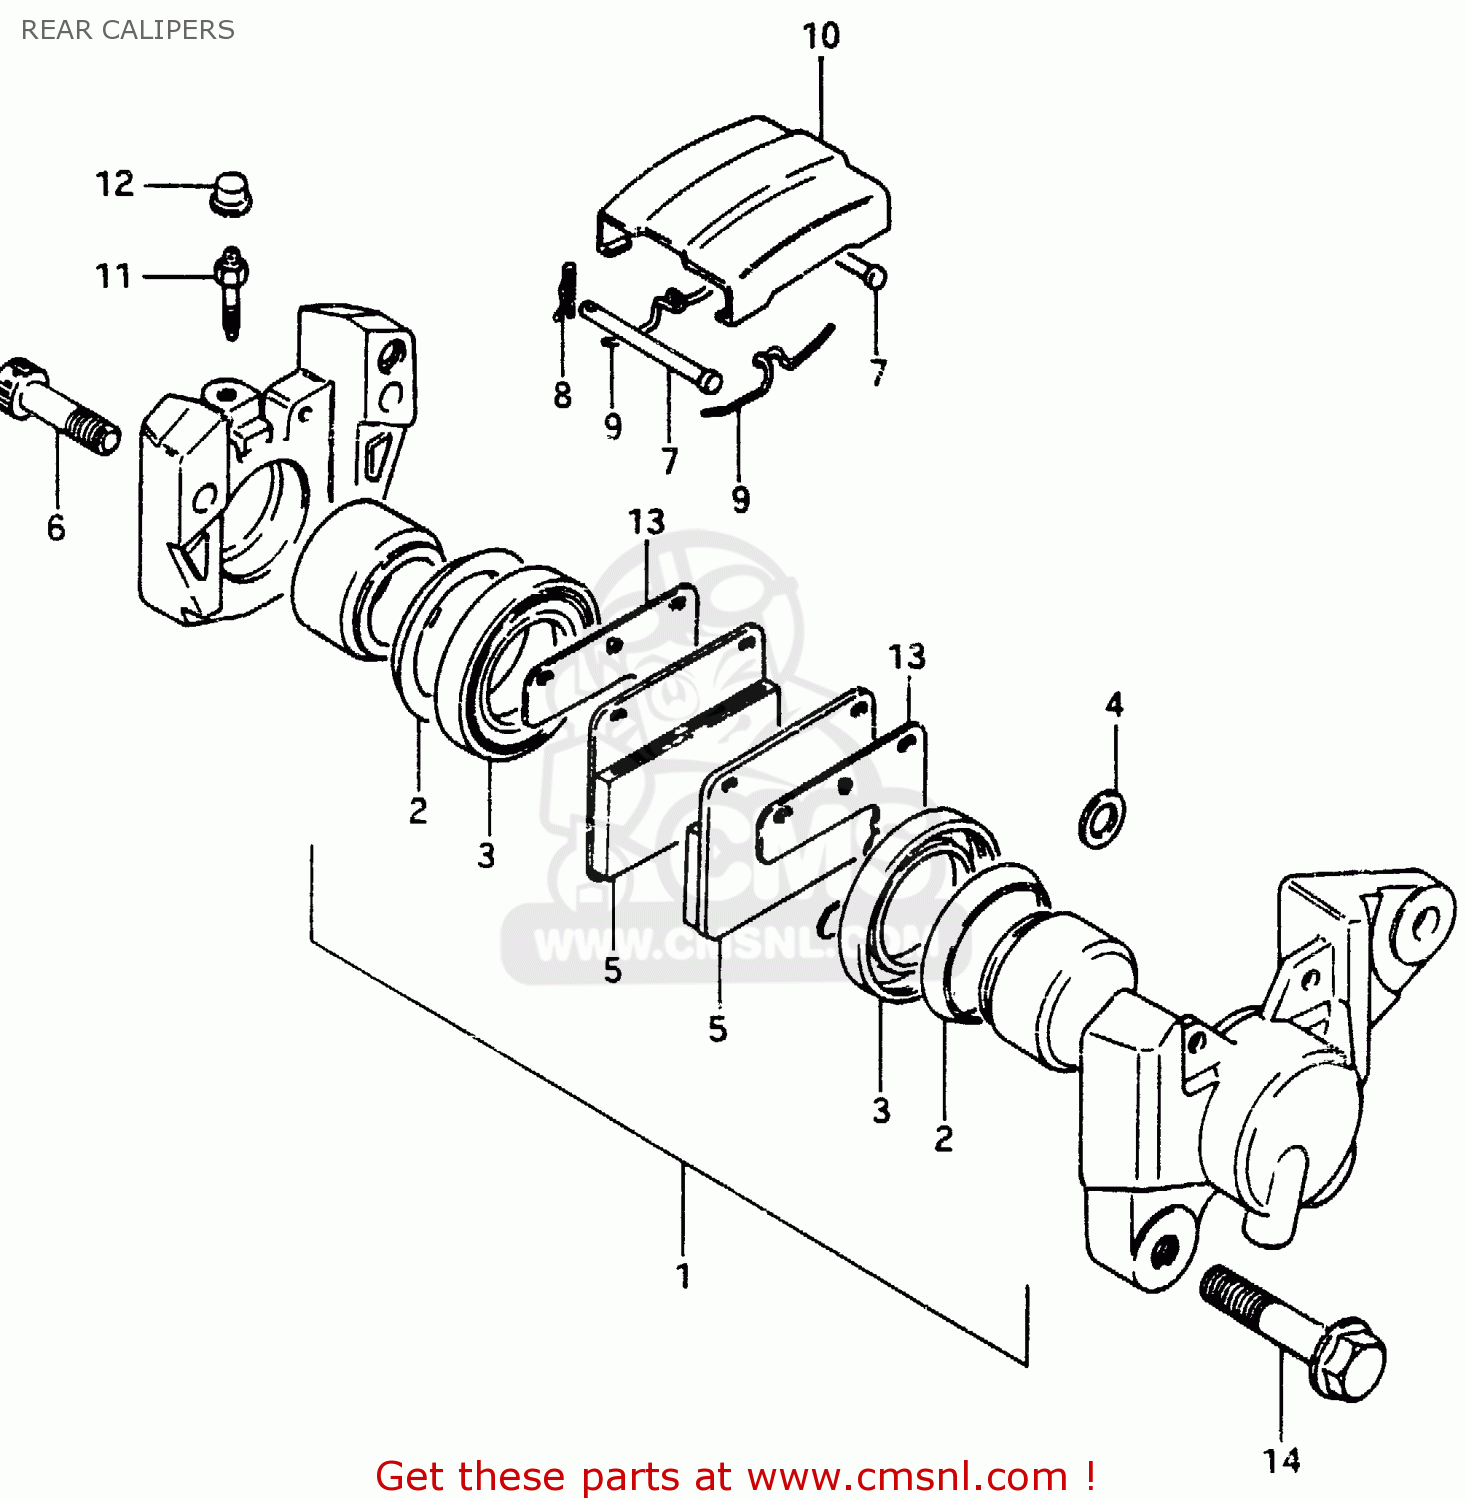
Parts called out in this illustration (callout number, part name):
1	PISTON SET
2	SEAL,PISTON
3	BOOT,PISTON
4	SEAL,JOINT
5	PAD
6	BOLT,CALIPER HOUSING
7	PIN,PAD
8	CLIP,PAD PIN
9	SPRING
10	COVER,DUST
11	BLEEDER
12	CAP,BREATHER
13	SHIM,RR CALIPER
14	BOLT 10X30
